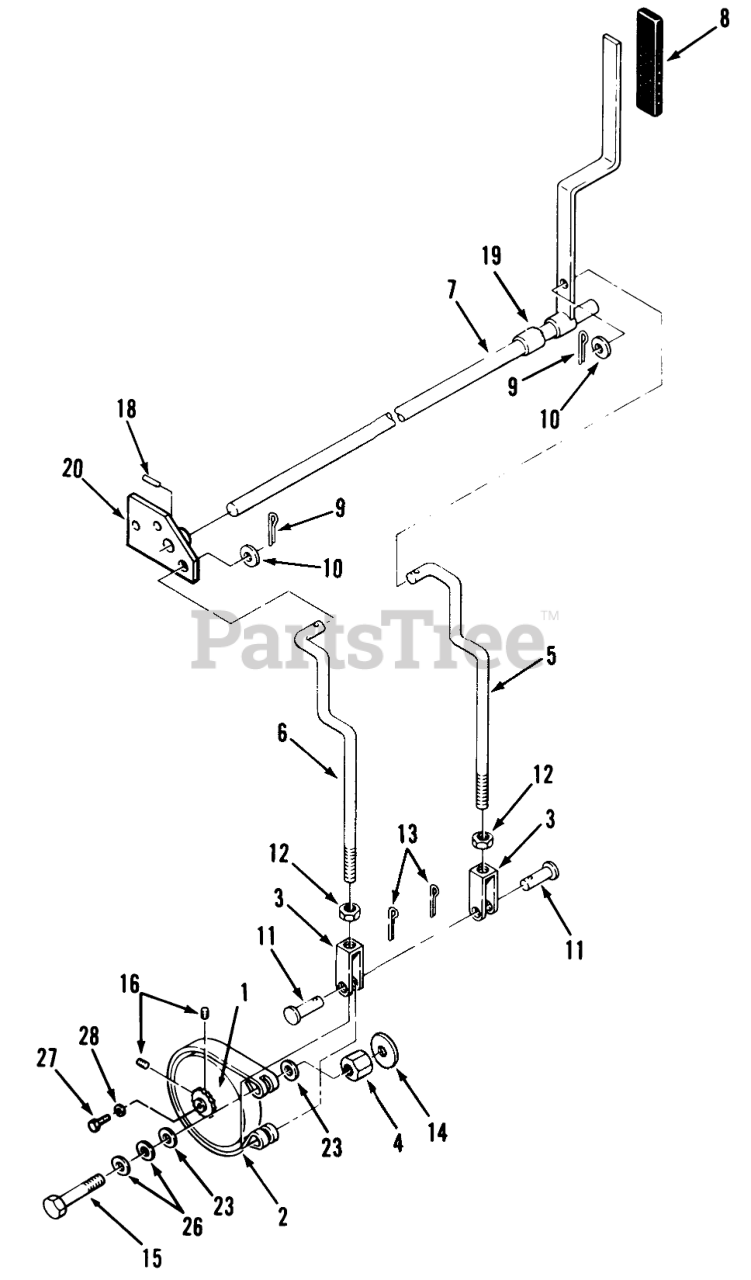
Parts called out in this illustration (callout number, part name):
1	ASS'Y-DRUM SPROCKET
2	BRAKE-BAND
3	ASSY-YOKE BRAKE
4	NUT-COUPLING
5	ROD-BRAKE L.H.
6	ROD-BRAKE R.H.
7	ASSY-PARKING BRK
8	GRIP BRAKE20258-K
9	Cotter Pin
10	WASHER 5/16 SAE
11	Clevis Pin 5/16 x 1 1/4
12	Nut-Lock
13	Cotter Pin
14	WASHER
15	Bolt
16	SCREW-SET
18	Roll Pin
19	SPACER-PARKING BR B
20	ASSY-PARKING BRK B
23	Washer
26	WASHER-SPRING
27	H H C S
28	WASHER
